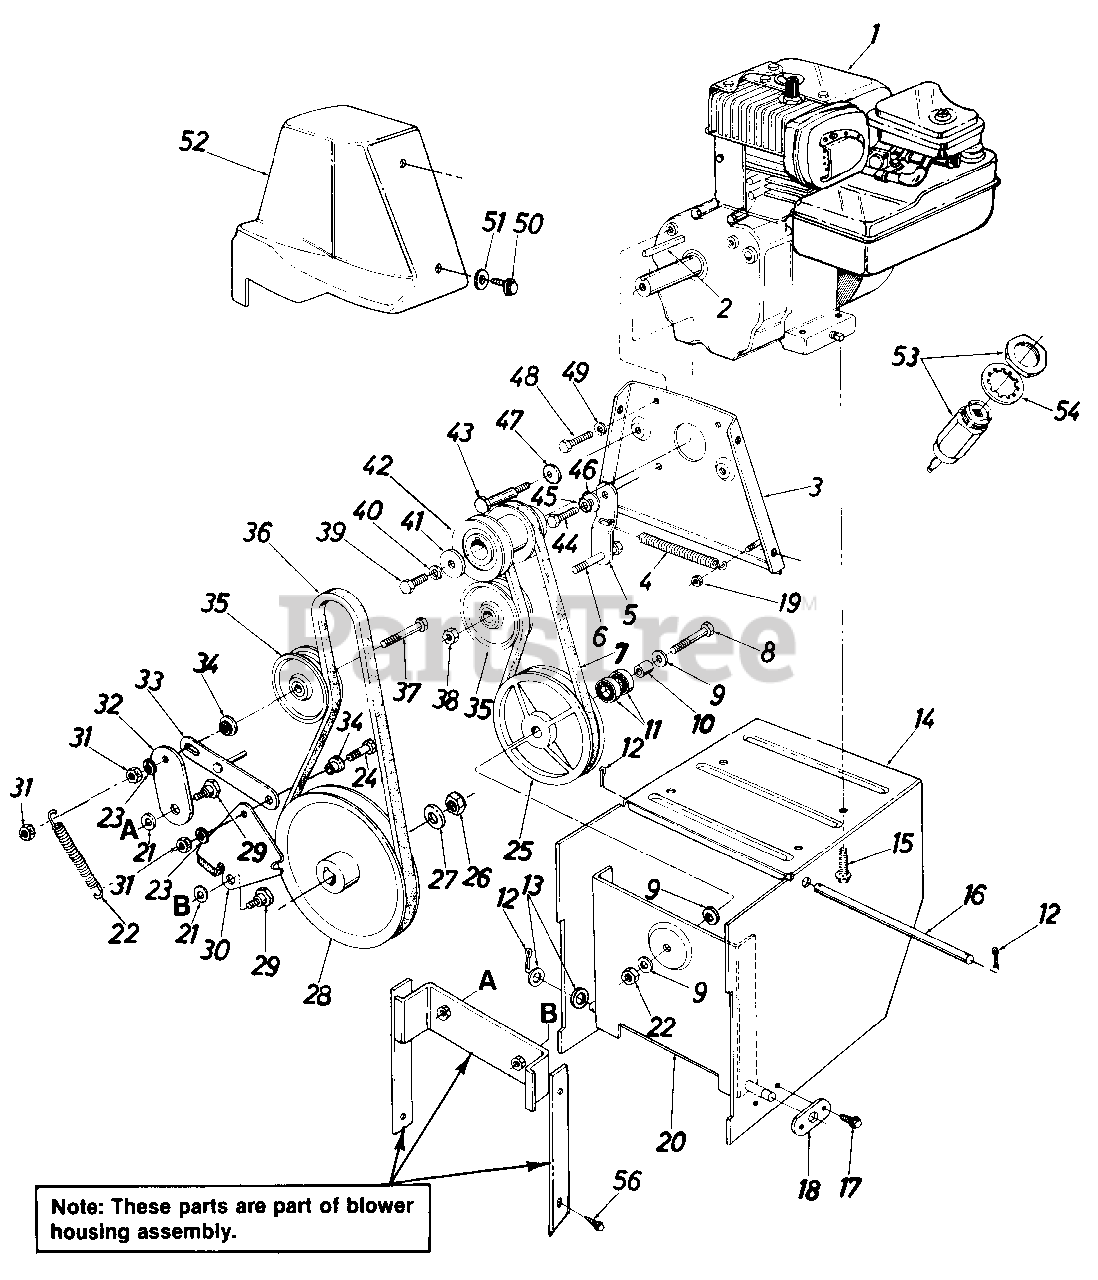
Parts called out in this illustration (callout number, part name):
2	Sq. Key 3/16" x 1.50" Lg.
3	Engine Plate Ass'y.
4	Extension Spring .50" O.D. x 4.25" Lg.
5	Drive Clutch Idler Brkt.
6	Hex Bolt 3/8-24 x 1.25" Lg. *
7	"V"-Belt 318" x 29.0" Lg.
8	Hex Bolt 3/8-24 x 1.50" Lg.*
9	Bell-Wash. .40" I.D. x .88" O.D. x .06
10	Spacer .38" I.D. x .62" O.D. x.75" Lg.
11	Ball Brg. .62" I.D. x 1.38" O.D. x .44
12	Cotter Pin 3132" Dia. x .75" Lg. *
13	Fl-Wash. .53" I.D. x 1.00" O.D. x .125
14	Frame Ass'y.
15	Hex Wash. Hd. Self-Tap Scr. 3/8-16 x 1.25" Lg.
16	Shaft .50" Dia. x 9.50" Lg.
17	Hex Wash. Hd. Self-Tap Scr. 1/4-20 x .50" Lg.
18	Axle Bracket
19	Hex L-Nut 1/4-20 Thd.
20	Drive Pulley Support Brkt. Ass 'y.
21	Bell-Wash. .40" I.D. x 1.13" O.D.
22	Extension Spring .50" O.D. x 3.97" Lg.
23	L-Wash. 3/8" I.D.*
24	Hex Scr. 3/8-16 x 1.25" Lg.
25	6.00" O.D. Drive Pulley Ass'y. (Incl. Ref. #11)
26	Hex Jam Cent. L-Nut 5/8-18 Thd.
27	Fl-Wash. .64" I.D. x .94" O.D. x .06
28	1/2" V-Pulley .625" I.D. x 7.50" O.D.
29	Shld. Bolt .625" Dia. x .170" Lg. (3/8-16)
30	Brake Bracket Ass'y.
31	Hex Ins. L-Nut 318-16 Thd.
32	Auger Clutch Idler Brkt.
33	Brake Linkage Ass'y.
34	Shld. Spacer.625" I.D.
35	Flat Idler 2.25" O.D.
36	"V"-Belt 3/8" x 38" Lg.
37	Hex Bolt 3/8-16 x 2.25" Lg.*
38	Hex Ins. Jam L-Nut 3/8-24 Thd.
39	Hex Bolt 3/8-24 x 1.50" Lg.
40	L-Wash 3/8" I.D.*
41	Fl-Wash .40n l.D. x 1.25" O.D.
42	Double Groove Engine Pulley
43	Shld. Scr. .498" x 8.0n Lg.
44	Hex Bolt 5/16-24 x 1.00"*
45	L-Wash 5/16" I.D.
46	Shld. Spacer.320" I.D.
47	Bell-Wash. .40" l.D. x .88" x .06
48	Hex Bolt 5/16-24 x .62" Lg.*
49	L-Wash. 5/16" I.D.
50	Hex Wash. Hd. Self-Tap Scr. 1/4-20 x .50" Lg.
51	Fl-Wash. .28n l.D. x .75" O.D. x .06
52	Belt Cover
53	Ignition Switch
54	Int. L-Wash. 5/8" I.D.
56	Hex Wash. Hd. Self-Tap Scr. 3/8-16 x .75" Lg.
